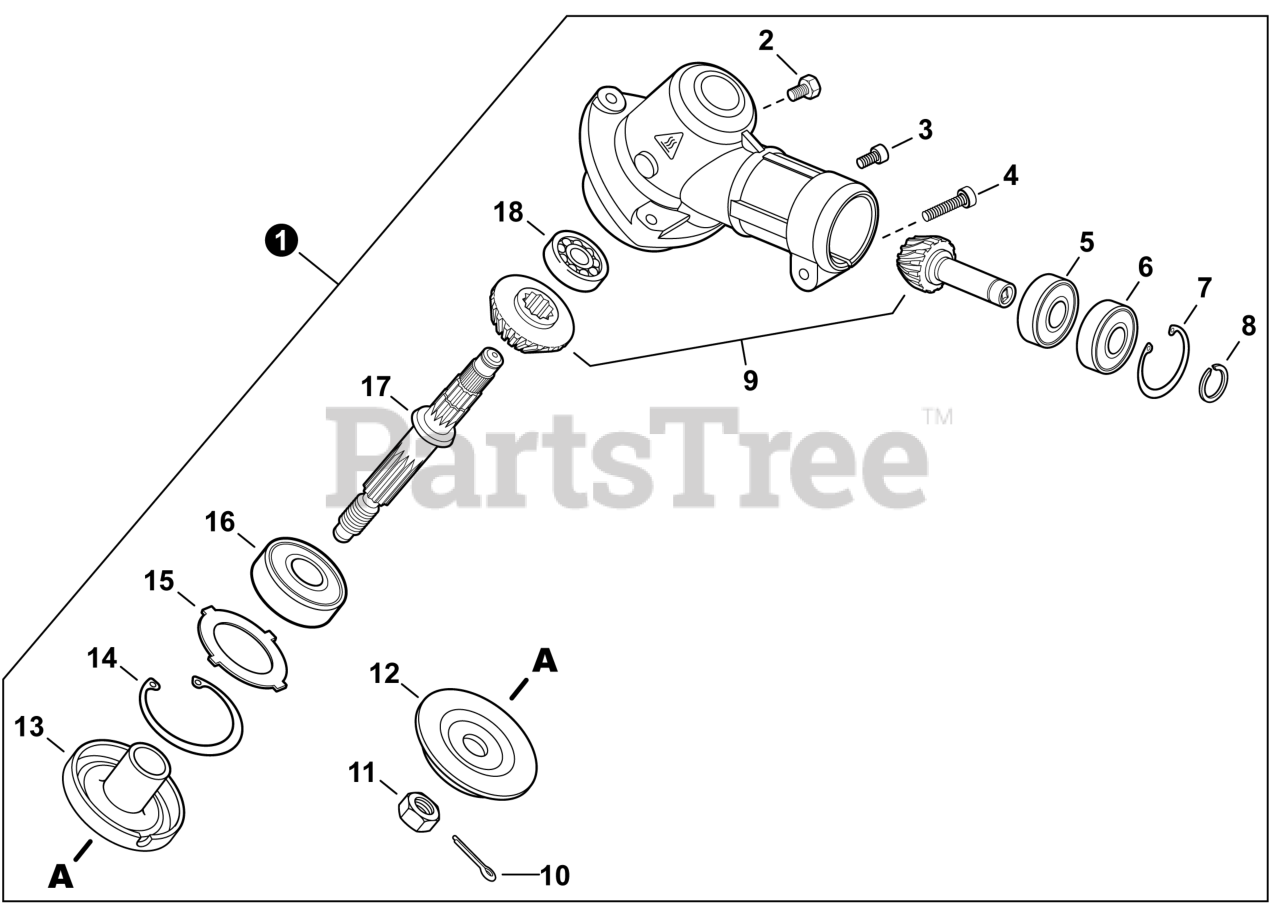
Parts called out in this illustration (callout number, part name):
1	GEAR CASE ASSY
2	BOLT M8×8
3	BOLT, TORX 5×12
4	BOLT, TORX 5×25
5	BEARING, BALL 609A
6	BEARING, BALL 609ZA
7	RING, SNAP Ø25
8	RING, SNAP Ø9
9	GEAR SET
10	PIN, COTTER 2×22
12	PLATE, ADAPTOR - LOWER
13	PLATE, ADAPTOR - UPPER
14	RING, SNAP Ø32
16	BEARING, BALL 6201
17	SHAFT, GEAR
18	BEARING, BALL 629A
